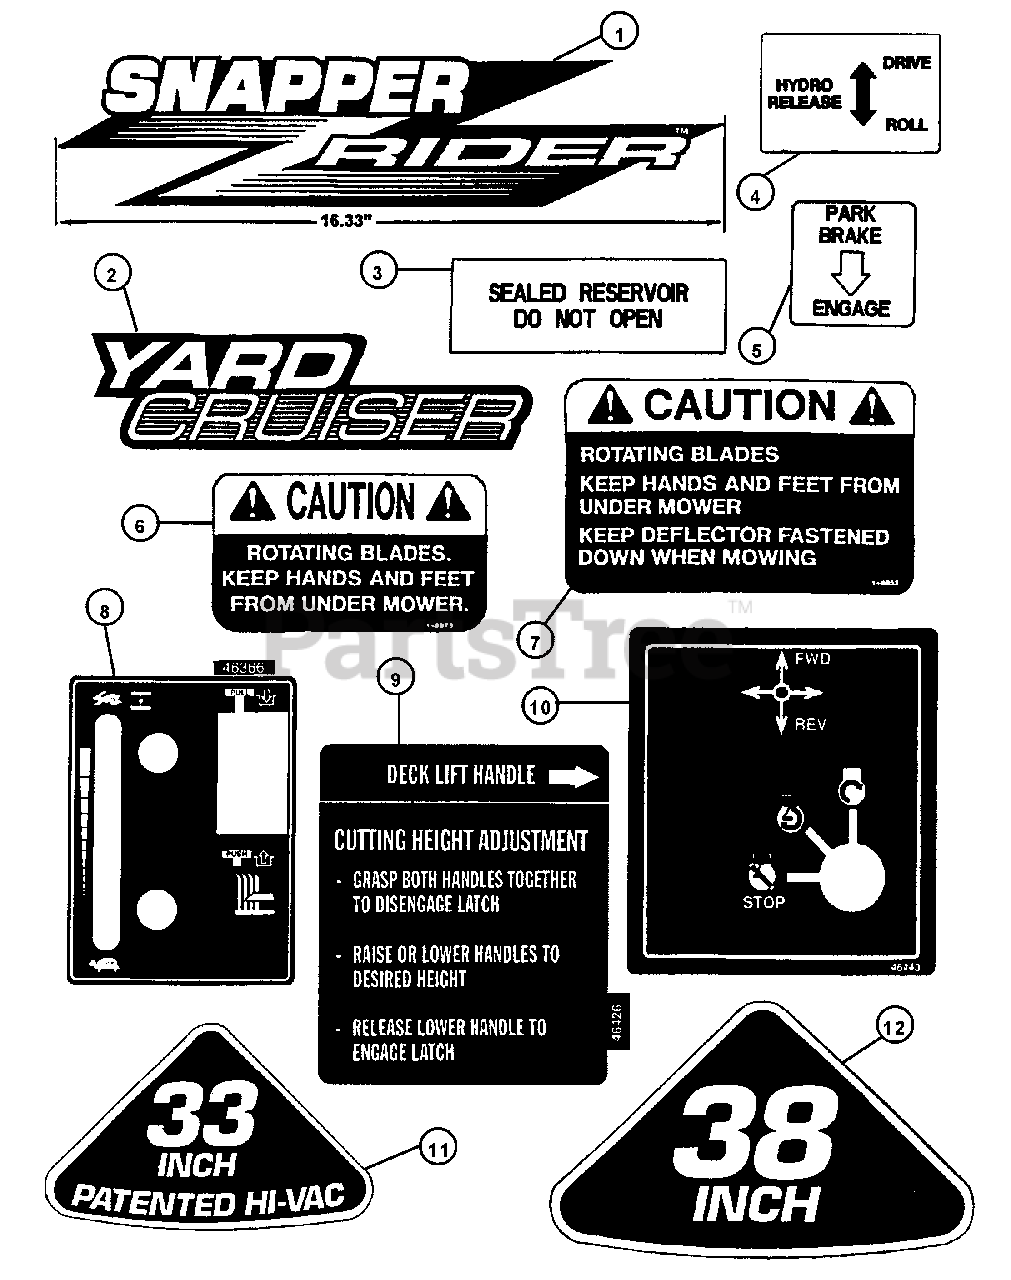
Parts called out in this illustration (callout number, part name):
1	DECAL, SNAPPER Z Rider
2	DECAL, Yard Cruiser
3	DECAL, Hydro Reservoir
4	DECAL, Hydro Release
5	DECAL, Parking Brake
6	DECAL, Caution
7	DECAL, Caution
8	DECAL, Engine Control
9	DECAL, Deck Height
10	DECAL, Ignition Switch
11	DECAL, 33" Hi-Vac
12	DECAL, 38 Inch
